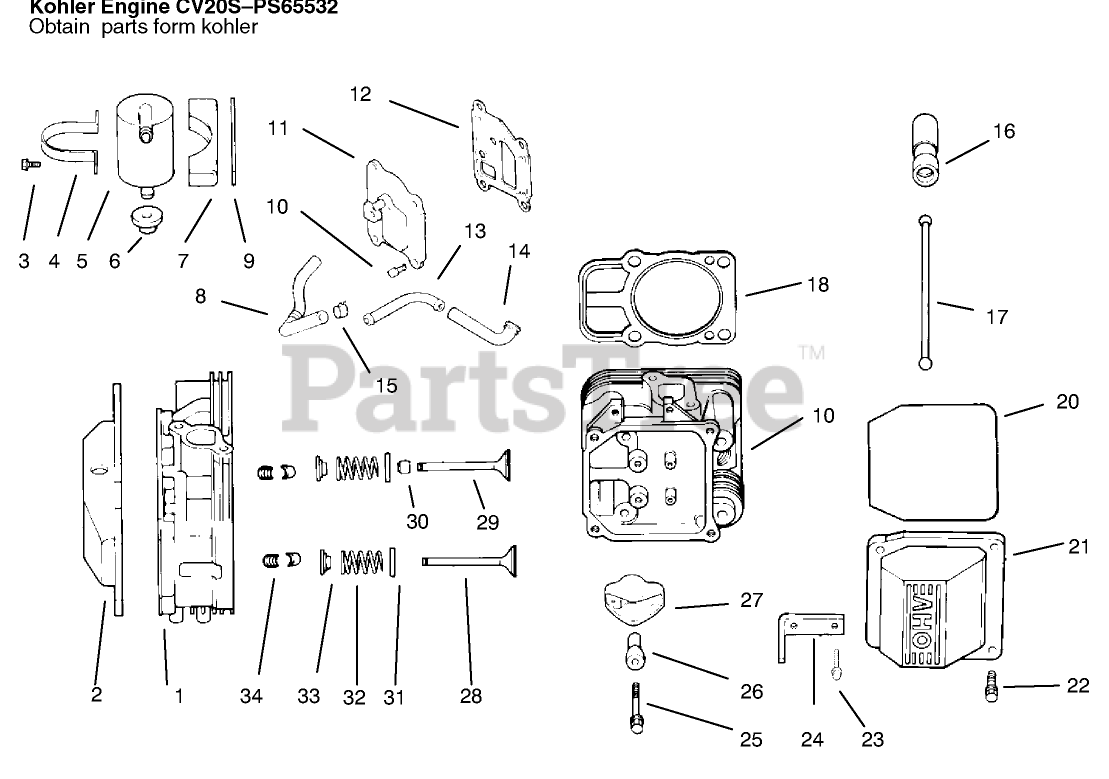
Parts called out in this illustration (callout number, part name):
1	Head ASM-#1 Cylinder (Only On: 72103, 72083)
2	Cover-Rocker (Only On: 72103)
3	Kit-Breather INCL 4 (Only On: 72103)
4	Grommet-Rubber (Only On: 72103)
5	Cover-Breather (Only On: 72103)
7	Hose-Breather (Only On: 72103)
8	Kit-Retainer
9	Cap-Valve Spring
10	Spring-Valve
11	Retainer-Spring
12	Valve-Exhaust
13	Valve-Intake
14	Seal-Valve Stem
15	Fitting (Only On: 72103)
16	Hose-Breather (Only On: 72103)
17	Lifter-Valve
18	Rod-Push (Only On: 72103,72083)
19	Gasket-Cylinder Head
20	Head ASM-#2 Cylinder (Only On: 72103, 72083)
21	Arm-Rocker (Only On: 72103,72083)
22	Ball-Rocker Pivot
24	Cover-Rocker (Only On: 72103)
25	Screw
27	Strap-Lifting
